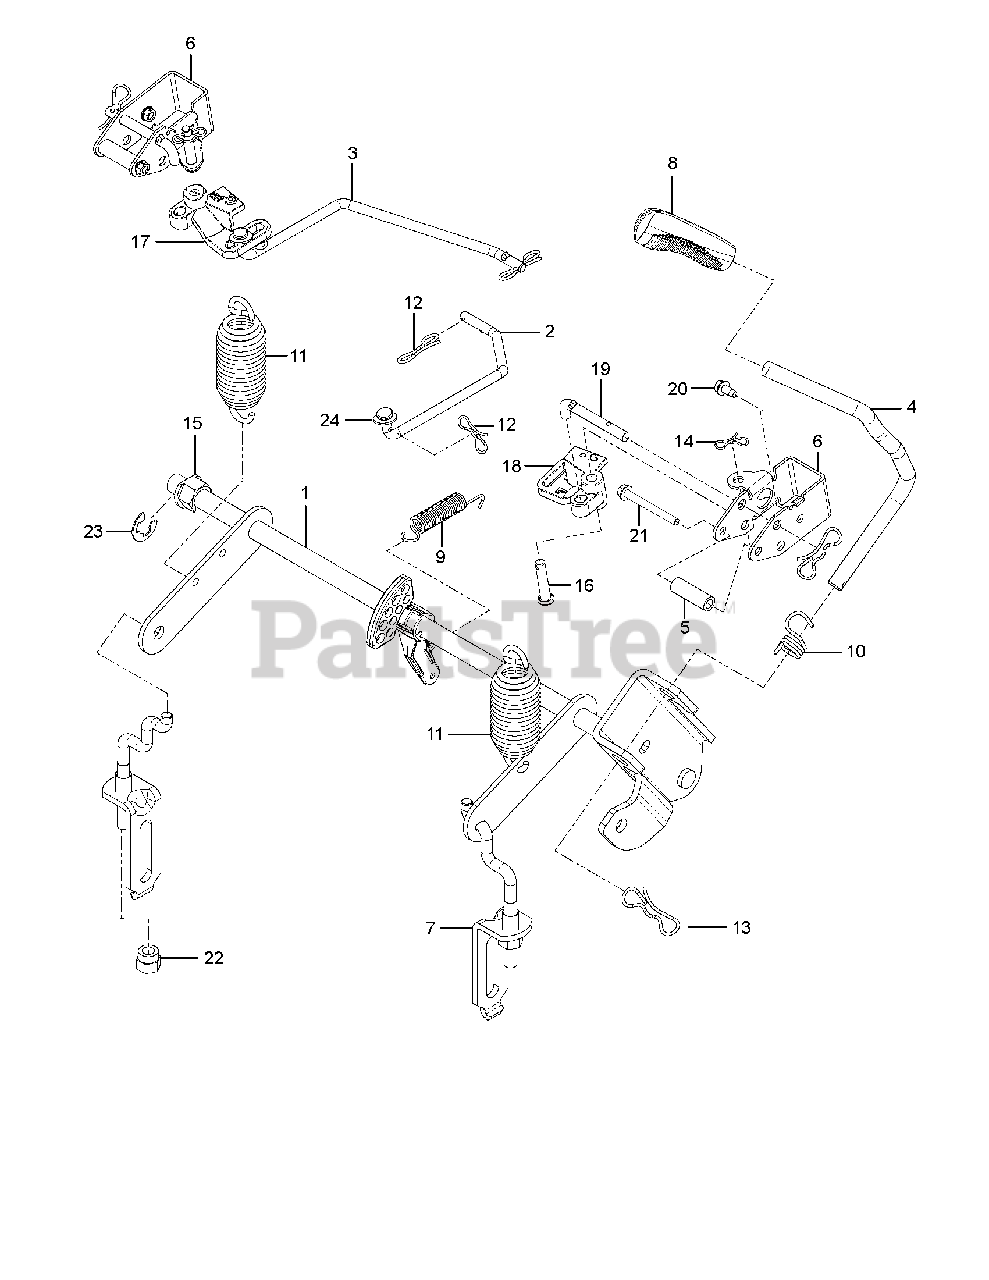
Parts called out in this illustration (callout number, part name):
1	SHAFT.ASM.RZ.DECK.LIFT.SRV
2	LINK.BRAKE.PARK.UPPER.LH
3	LINK.BRAKE.PARK.UPPER.RH
4	LIFT.LEVER.ASM.RZ.SERVICE
5	SPACER.334.ID.5.OD.1.5.L
6	BRACKET.BELLCRANK.PBRAKE X431
7	LINK.ASM.RZ.LIFT.SERVICE
8	GRIP.HANDLE.LIFT.PVC.428
9	RETURN.BRAKE.PARK.AUTO
10	SPRING.TORSION.LIFT.HANDLE
12	PIN COTTER;LOCKING;BOWTIE;1IN
13	PIN.COTTER.7/16.BOW TI.
14	PIN.COTTER.5/16.BOW TI
15	PLASTIC NUT
16	PIN.5.16X1.5
17	BELLCRANK.RH
18	BELLCRANK.LH
19	ROD.PUSH.BRAKE
20	SCREW.1/4-20X5/8
21	SCREW THD;ROLL;1/4-20 X 2.25
22	NUT, LIFT LINK 7/16-20
23	RETAINING RING LT
24	WASHER
